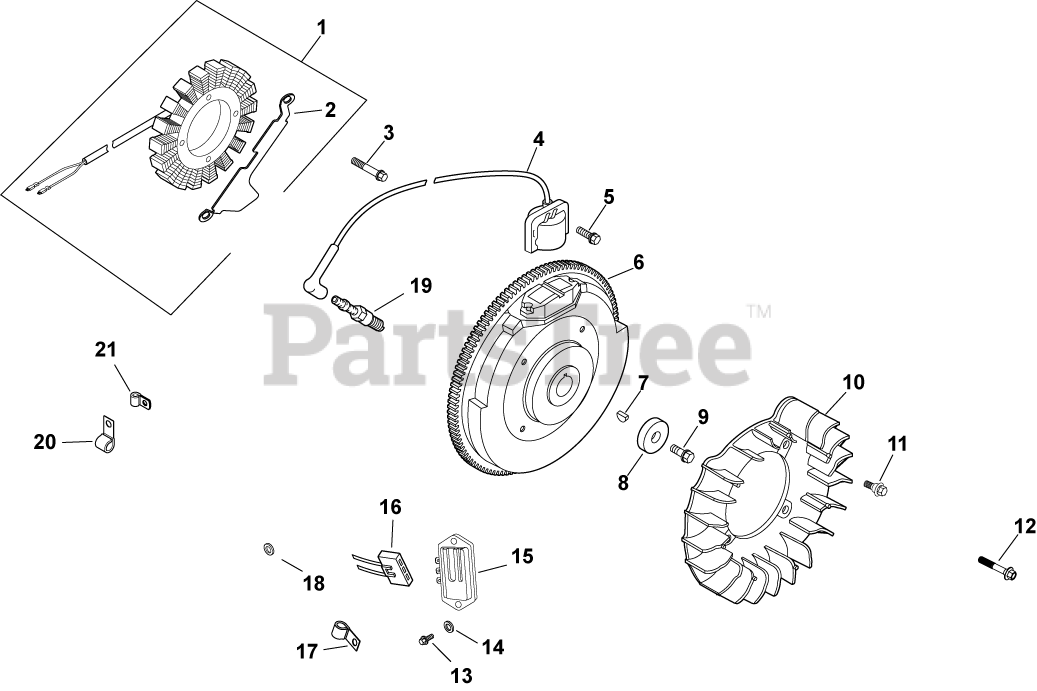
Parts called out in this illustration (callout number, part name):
1	KIT, 15 / 20 AMP STATOR
2	BRACKET, STATOR WIRE
3	SCREW, M5X0.8X25 - (#25086402S)
4	MODULE, IGNITION-USE 24 584 45-S
5	SCREW, FLG THD FRM M5X.8X20-(#25086399S)
6	FLYWHEEL, PAINTED-USE 24 025 59-S
7	KEY, 3/16" X 5/8"
8	WASHER, FLAT 13/32"
9	SCREW, FLG M10X1.5X45 - (#25086361S)
10	FAN (WITH HOLE)-USE 24 157 16-S
11	BOLT, SHOULDER
12	SCREW, FLG M6X1.0X10
13	SCREW, PHL HD #11-16X7/8"
14	WASHER, FLAT 3/16"
15	REG/RECT-15 AMP (KM)-USE 41 403 10-S
16	CONNECTOR, BODY (KM)-USE 25 155 41-S
17	CLIP, CABLE
18	WASHER, FLAT 1/4" (O.D. 1/2")
19	PLUG, SPARK (STD)
21	CLIP, CABLE - USE 24 154 10-S
